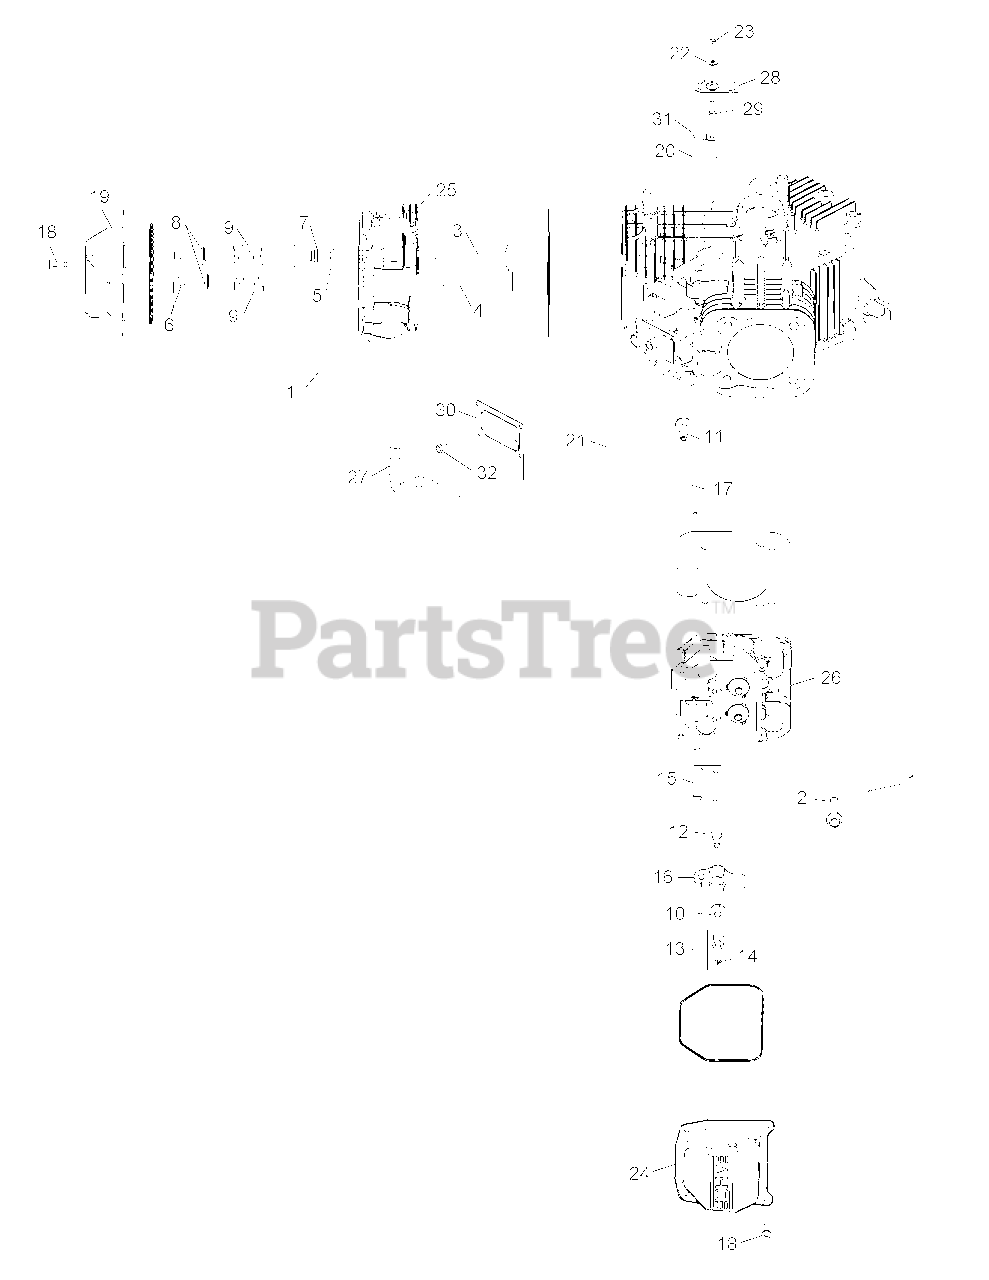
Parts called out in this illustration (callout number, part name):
1	Cylinder Head Gasket Kit
2	Flange Screw, M10 x 1.5 x 90
4	Exhaust Valve
5	Spacer (.010")
6	Retainer Kit
7	Valve Band Seal
8	Valve Spring Cap
9	Valve Spring
10	Rocker Arm Pivot
13	Hex Nut Assembly (Inc. #14)
18	Pan Head Screw
20	Breather Reed
21	Breather Filter
22	Sealing Washer
23	Lock Nut, M5 x 8
24	Rocker Cover
25	Cylinder Head Assembly Kit, #1
26	Cylinder Head Assembly Kit, #2
27	Breather Hose
28	Breather Cover
30	Breather Media Cover
31	Reed Retainer
32	Thread Forming Screw
